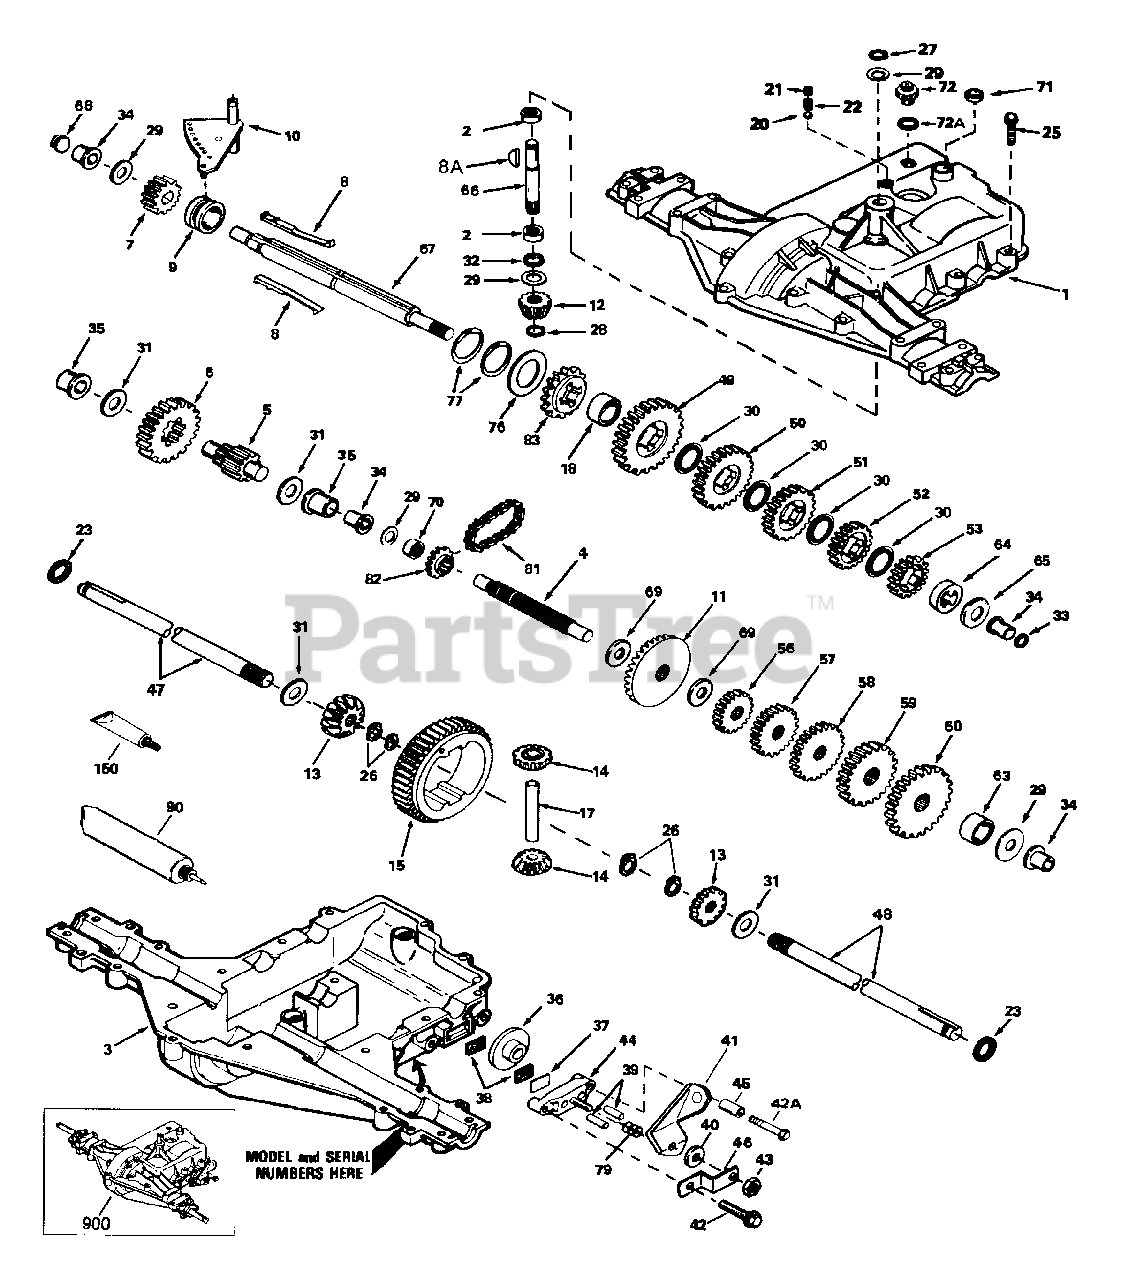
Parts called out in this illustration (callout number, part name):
1	Cover, Transaxle
2	Bearing, Needle
3	Case, Transaxle
4	Shaft, Counter
5	Shaft and Pinion Assembly, Output
6	Gear, Output
7	Gear, Spur, 15 Teeth
8	Key, Shift
8A	Key, Woodruff
9	Collar, Shifter
10	Rod and Fork Assembly, Shift
11	Gear, Bevel, 42 Teeth
12	Bevel Pinion, Input
13	Gear, Bevel
14	Gear, Bevel Pinion
15	Gear, Ring
17	Pin, Drive
18	Spacer, Neutral
20	Ball, Steel 5/16" diameter
21	Set Screw 3/8-16 x 3/8
23	Ring, Seal
25	Screw, Flanged Hex Head, Thread Forming 1/4-20 x 1-1/4
26	Ring, Retainer (4 Required, Package of 2)
27	Ring, Retainer
28	Ring, Retainer
29	Washer, Thrust
30	Washer, Thrust
32	"O" Ring
33	Seal, Square Cut
34	Bushing, Flanged
35	Bushing, Flanged
36	Disk, Brake
37	Plate, Brake Pad
38	Pad, Brake
39	Pin, Dowel
40	Washer, Flat
41	Lever, Brake
42	Screw, Flanged Hex Head, Thread Forming 1/4-20 x 1-1/4
42A	Screw 1/4-20 x 2-1/4
43	Locknut 5/16-24
44	Holder, Brake Pad
46	Bracket, Brake Lever
47	Axle 11-5/16" long
48	Axle 16-1/2" long
49	Gear, Spur, 37 Teeth (1st)
50	Gear, Spur, 30 Teeth (2nd)
51	Gear, Spur, 25 Teeth (3rd)
52	Gear, Spur, 22 Teeth (4th)
53	Gear, Spur, 19 Teeth, Steel (5th)
56	Gear, Spur, 12 Teeth (1st)
57	Gear, Spur, 20 Teeth (2nd)
58	Gear, Spur, 25 Teeth (3rd)
59	Gear, Spur, 28 Teeth (4th)
60	Gear, Spur, 31 Teeth (5th)
65	Washer, Thrust
66	Shaft, Input
67	Shaft, Brake, 4 Keyed
69	Washer, Thrust
71	Seal, Square Cut
72	Plug, Threaded 9/16-18
72A	"O" Ring
76	Washer, Thrust
77	Ring, Retaining, Inverted (Package of 2)
79	Spring, Brake
81	Chain, Roller (Number 41 Chain, 24 Links)
82	Sprocket, 9 Teeth (Reverse)
83	Sprocket, 18 Teeth (Reverse)
90	Grease, Bentonite, 32 Ounce Bottle
150	Gasket Eliminator (Loctite #515)
900	Replacement Transaxle
